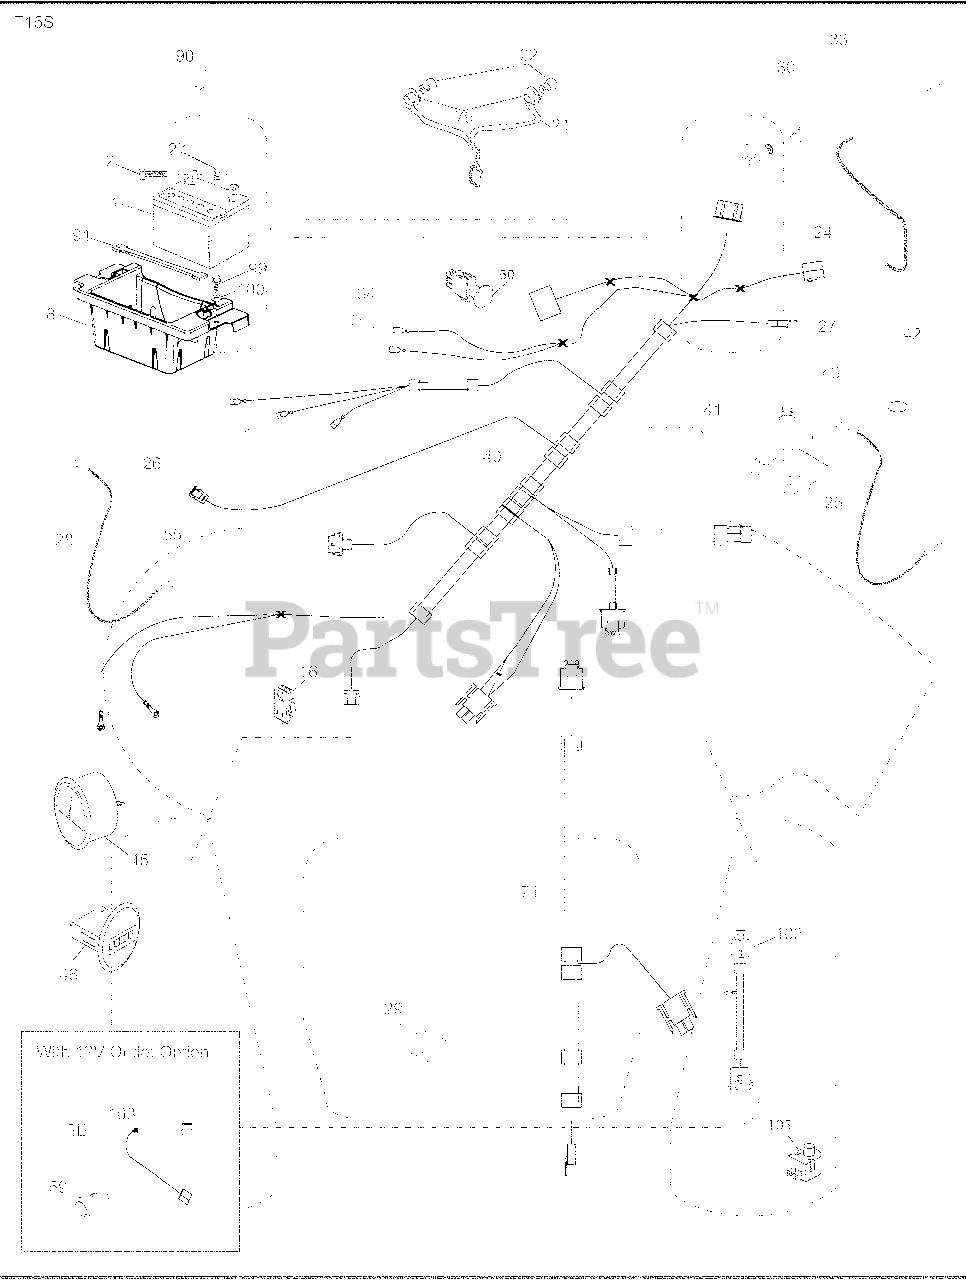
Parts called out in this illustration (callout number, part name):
1	Battery
2	Bolt Hex Head 1/4-20 x 3/4
8	Box Battery
16	Switch Interlock Push-In
21	Harness Socket Light w/4152J
22	Bulb Light
24	Cable Battery 8"
25	Cable Starter
27	Nut Keps Hex 1/4-20 unc
28	Cable, Ground
29	Switch, Seat
30	Switch, Ign
34	Switch Light / Reset
40	Harness Ign. Dash
41	Screw Thd Cut 1/4-20 x 1/2
42	Cover, Terminal
43	Solenoid
45	Ammeter Gauge Round Snap-In
46	Gauge Hrmtr
50	Switch PTO
55	Screw Thdrol 5/16-18 x 3/4 TYTT
59	Outlet 12-Volt
71	Harness Ign.
79	Socket Asm Bulb Twistlock
90	Cover Terminal
91	Strap Battery Mount Front
99	Screw Hexwsh Thdrol 1/4-20 x 3/4
100	Washer 9/32 x 7/8 x 16 Ga.
102	Harness Pigtail
103	Harness 12-Volt Pigtail
105	Switch Reverse TT Pedal Control
